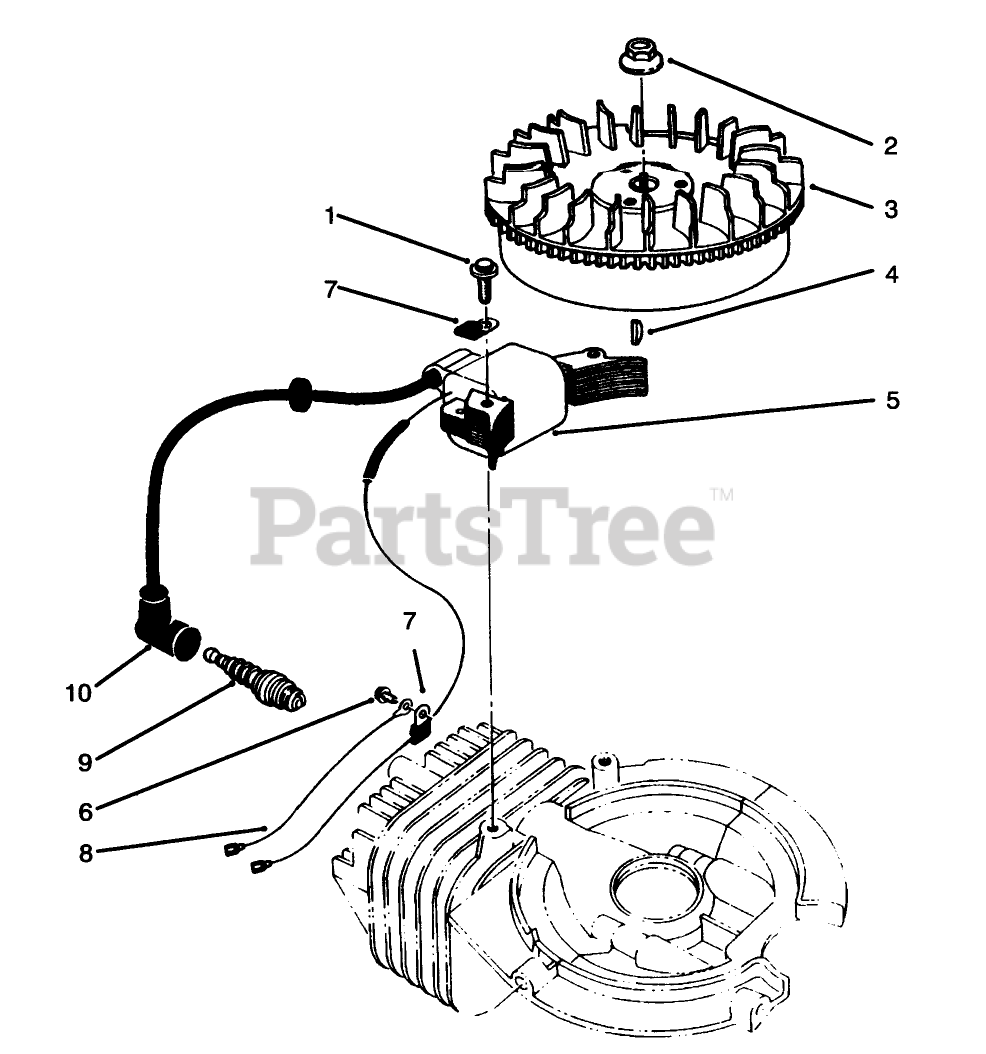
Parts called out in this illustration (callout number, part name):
1	SCREW
3	FLYWHEEL
5	ASM - MAGNETO COIL
7	CLAMP
9	SPARK PLUG
10	CAP-SPARKPLUG
